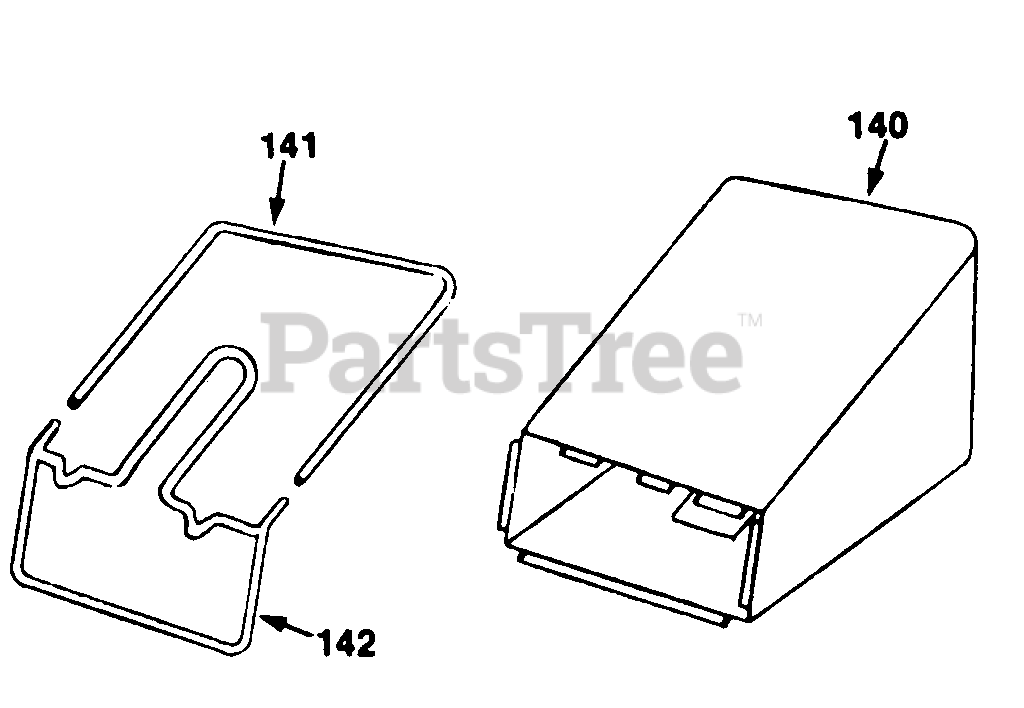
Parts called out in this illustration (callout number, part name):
140	Replacement Bag
141	Upper Frame
142	Lower Frame Ass'y
